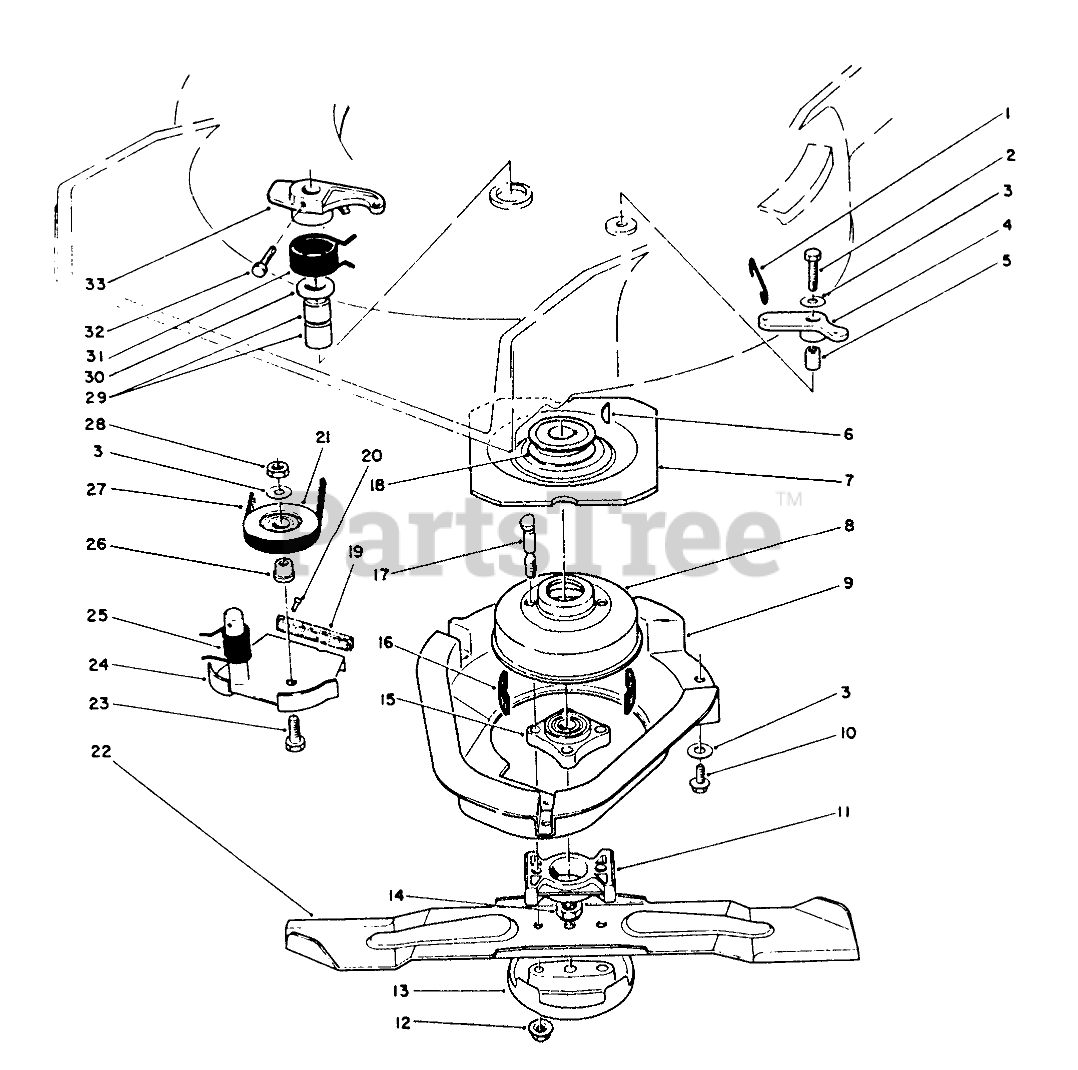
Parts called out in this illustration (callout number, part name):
1	LINK-CONTROL
2	SCREW-HH
3	WASHER-PLAIN
4	BELLCRANK
5	SLEEVE-BELLCRANK
6	KEY-WOODRUFF
7	Flywheel
8	Drum-Brake
9	SHIELD BBC
10	SCREW-HWHTF
11	SPACER-BLADE
12	NUT-LOCK
13	Anti Scalp Cup
14	NUT-LOCK, NI
15	HUB ASM
16	DAMPENER-VIBRATION
17	BOLT-BLADE
18	PULLEY
19	Pad-Brake
20	.185 DIA X .375 RT +
21	PULLEY-IDLER
22	BLADE-21in
23	SCREW-HH
24	Brake Plate (Incl. Ref. #19 & 20)
25	SPRING-TORSION
26	HUB-PULLEY, IDLER
27	V-BELT
28	NUT-LOCK, NI
29	BEARING
30	WASHER
31	SPRING-TORSION
32	SCREW-HH
33	LEVER
